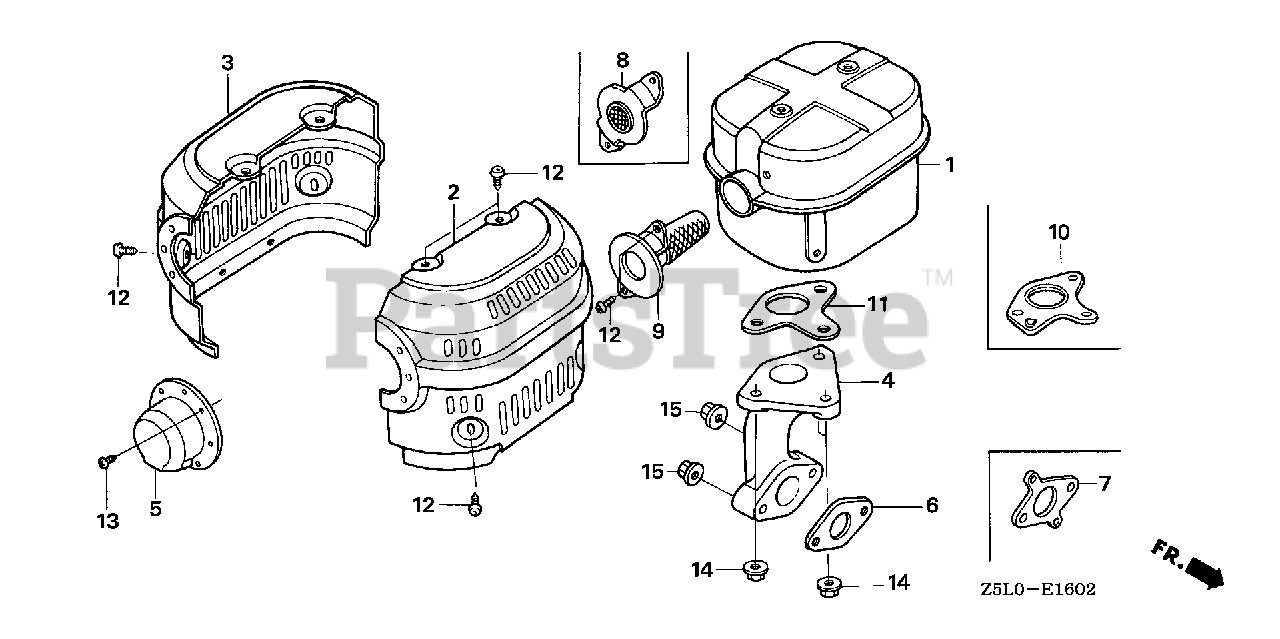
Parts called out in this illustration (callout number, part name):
1	MUFFLER
2	PROTECTOR, R. MUFFLER (ALUMINIZED)
3	PROTECTOR, L. MUFFLER (ALUMINIZED)
4	PIPE, EX.
6	GASKET, EX. PIPE
8	FLANGE, BAFFLE
9	ARRESTER, SPARK
10	GASKET, MUFFLER (ARRESTER)
11	GASKET, MUFFLER (NIPPON LEAKLESS)
12	SCREW, TAPPING (5X8)
14	NUT, FLANGE (8MM)
15	NUT, FLANGE (8MM)
